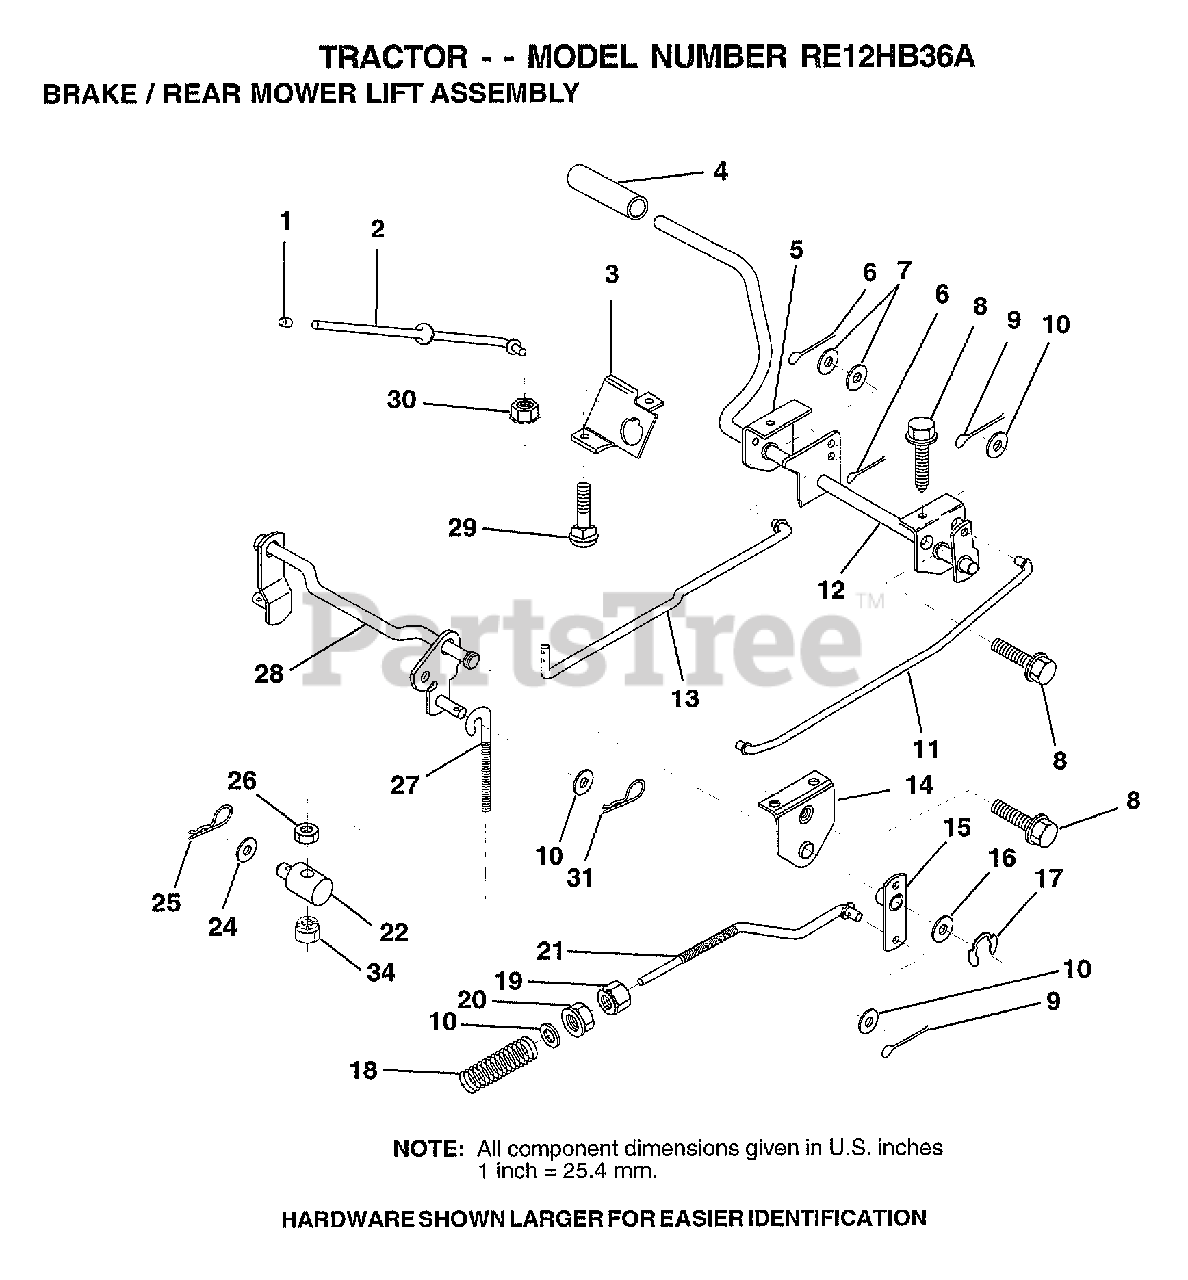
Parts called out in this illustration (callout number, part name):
1	PLUNGER CAP T
2	"ROD,PARK BRAKE"
3	"BRKT,PARK BRAKE"
4	FOOT PEDAL COVER
5	"BRKT,CLU PEDAL LH"
7	WASHER
8	SCREW LT
9	COTTER PIN
10	WASHER
11	"ROD,FRT BRAKE"
12	PEDAL ASM CL/BK36
13	"ROD,CLUTCH"
14	"BRKT,LIFT SHAFT"
15	PVT BRAKE ARM ASM
16	WASHER T
17	KLIP RING
18	SPRING ROD BRAKE
19	NUT
20	NUT
21	ROD.BRAKE.HYDRO
22	TRUNNION.LIFT.
24	WASHER
25	SPRING.RETAINER
26	LOCKNUT
27	"LINK, MOWER REAR"
28	LIFT ASM MOW REAR
31	RETAINER.SPRING
